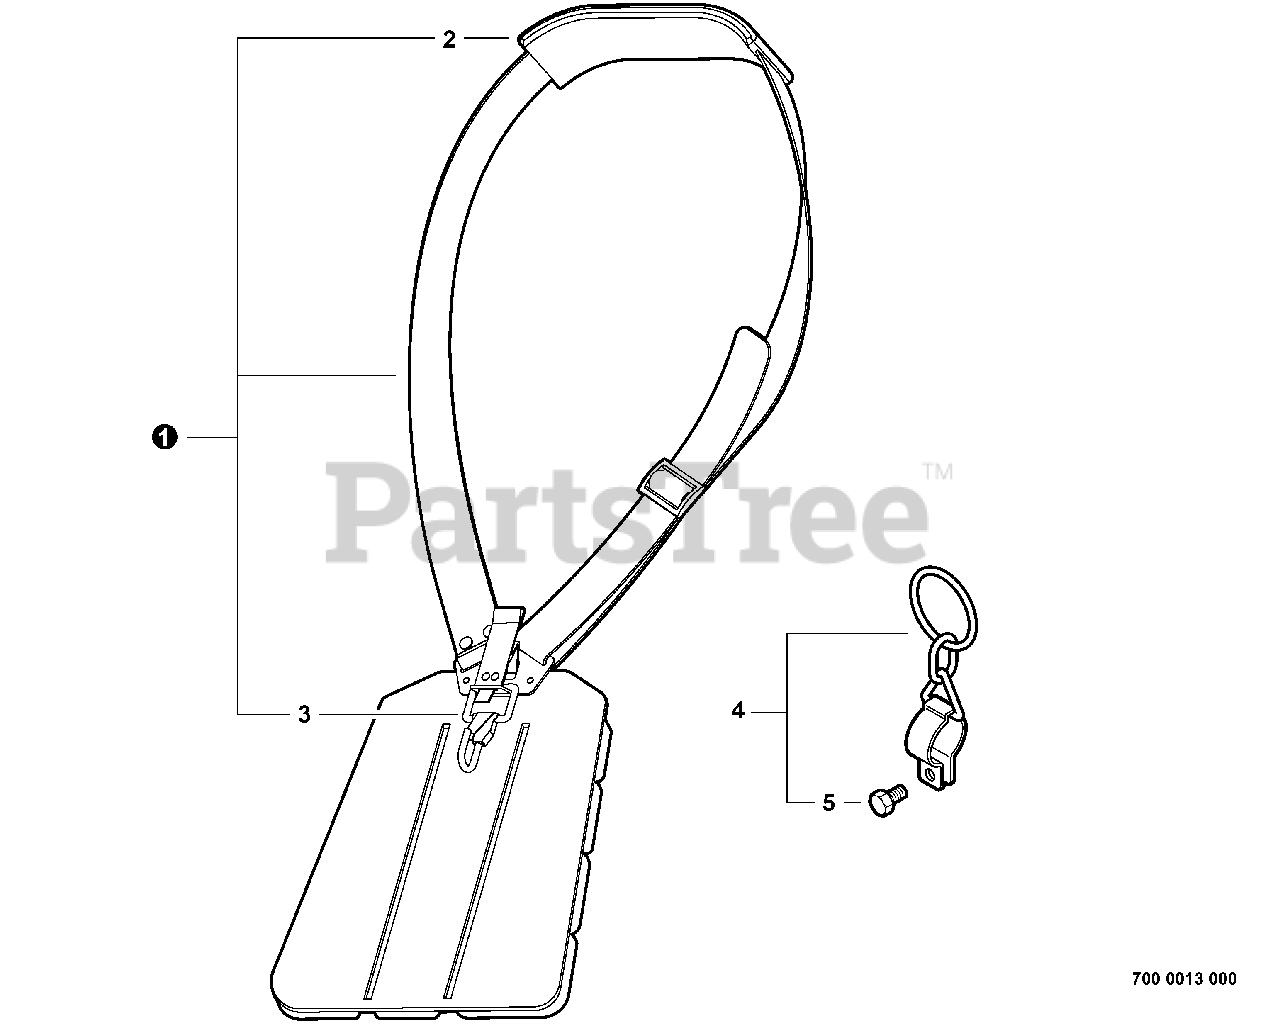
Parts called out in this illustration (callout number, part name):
1	HARNESS ASSY
2	PAD, SHOULDER
4	HANGER KIT
5	BOLT - 5X12
